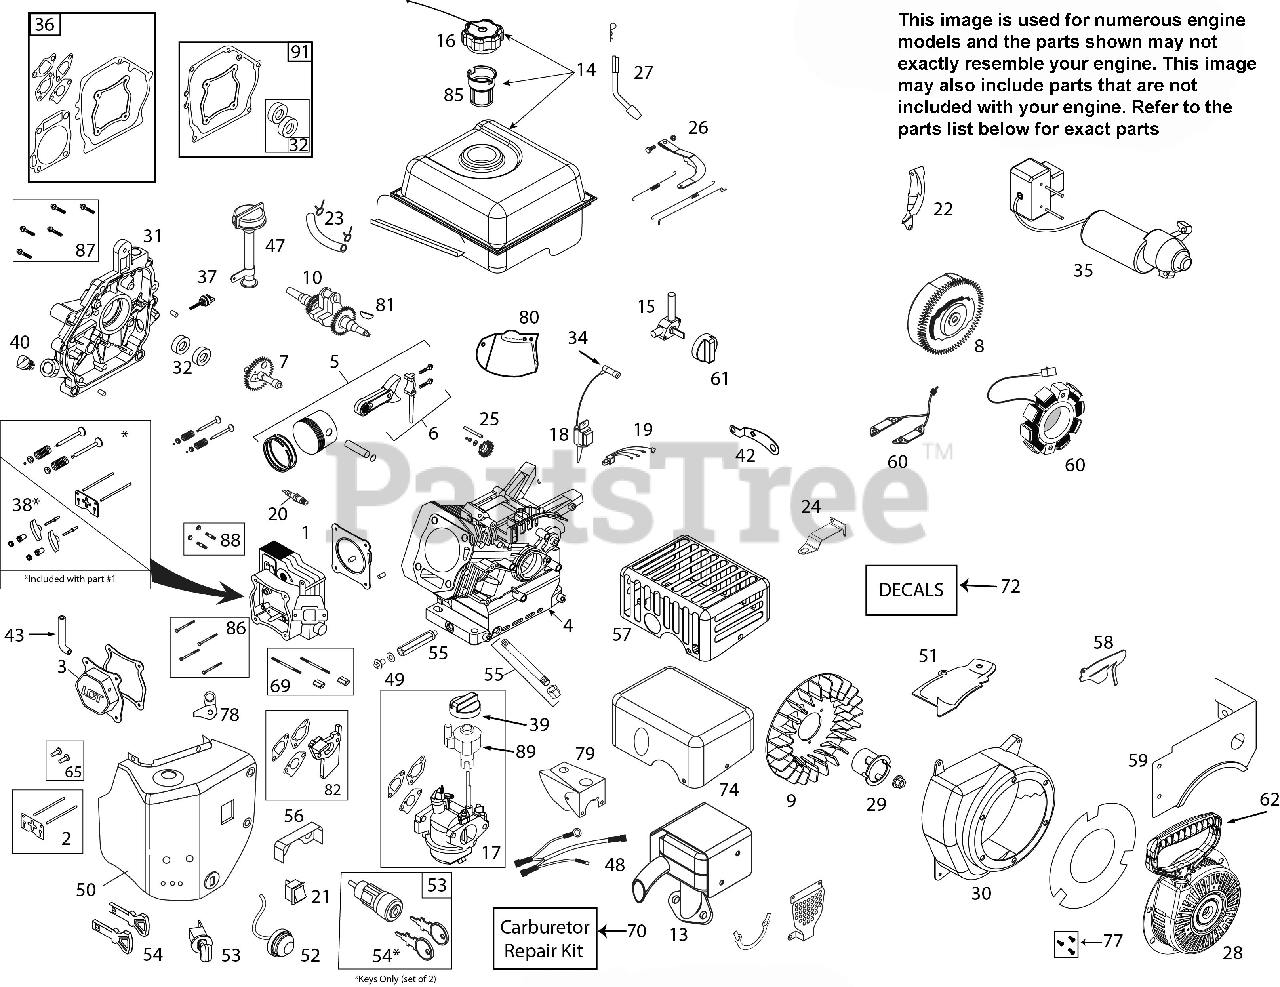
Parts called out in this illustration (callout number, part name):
1	CYLINDER HEAD ASSY (W/GASKET)
2	PUSH ROD & PLATE KIT (W/GASKT)
3	VALVE COVER (W/GASKET)
5	PISTON & ROD ASSEMBLY
7	CAMSHAFT - MCR
8	FLYWHEEL - ELECTRIC START
9	COOLING FAN - FLYWHEEL
10	CRANKSHAFT (#18 KEYED)
13	MUFFLER ASSEMBLY
14	FUEL TANK ASSY
15	FUEL TANK ON/OFF VALVE
16	CAP, FUEL TANK BLACK
17	CARBURETOR (W/GASKETS)
18	IGNITION COIL (CDI) (STANDARD)
20	SPARK PLUG, ARIENS AX
22	SHIELD - FLYWHEEL (ELECTRIC)
23	FUEL HOSE KIT 1/4-230MMW/CLMPS
24	SPEED CONTROL BRACKET (FIXED)
25	GOVERNOR GEAR ASSEMBLY
26	GOVERNOR ARM & LNK KIT 3600RPM
27	GOVERNOR ARM PADDLE
28	RECOIL STARTER ASSY RND-BLACK
29	STARTER CUP RND STYLE STARTER
31	CRANKCASE COVER ASSY W/GASKET
32	OIL SEAL KIT(2 PCS 3/4" CRANK)
34	SPARK PLUG BOOT (W/MTL SHIELD)
35	230V ELECTRIC STARTER
36	ENGINE GASKET KIT
37	SMALL BLACK OIL DIPSTICK
38	ROCKER ARM KIT (W/GASKET)
39	CHOKE CONTROL KNOB (RED)
40	NON-REMOVABLE PLASTIC PLUG
43	BREATHER TUBE
47	HIGH OIL-FILL TUBE/DIPSTICK
48	WIRE HARNESS, W/O ON/OFF SWITCH
49	OIL DRAIN PLUG (W/WASHER)
50	HEATER BOX, W/O ON/OFF SWITCH
51	SHIELD - CYLINDER
52	PRIMER BULB WITH HOSE-SNOW (RED)
53	SAFETY KEY SWITCH (W/KEYS) (RED)
54	KEY, PUSH/PULL LCT (2/PACKAGE)
55	FRONT OIL DRN PIPE & NUT ASSY
57	CE COMPLIANT MUFFLER SHIELD
58	GOV AND CARB SHIELD, COMPOSITE
59	FUEL TANK SKIRT
61	FUEL CONTROL KNOB (RED)
65	TAPPET KIT (SET OF 2)
69	CARBURETOR STUDS & COUPLNG KIT
70	CARBURETOR REPAIR KIT
74	MUFFLER HEAT SHIELD COVER
77	RECOIL BOLT KIT
78	BREATHER TUBE BRACKET
81	WOODRUFF FLYWHEEL KEY 5-PACK
82	CARBURETOR SPACER
85	FUEL TANK STRAINER
87	CC COVER BLT KIT 179-208-254CC
88	MUFFLER MTG STUD KIT
91	CRANKCASE GASKET KIT 208GEN1&2
97	MUFFLER MANIFOLD SHIELD
9999	HIGH ALT JET-208CC L10-1 CARB
9999	HARDWARE KIT (4 M6X10 FLG BLT)
9999	STARTER SWITCH SCREWS
9999	M6X30 ELEC STARTER MNTG BOLTS
9999	CLIPS, CARB THROTTLE LINKAGE
9999	BOTTLE 16 OZ 5W-30 OIL
